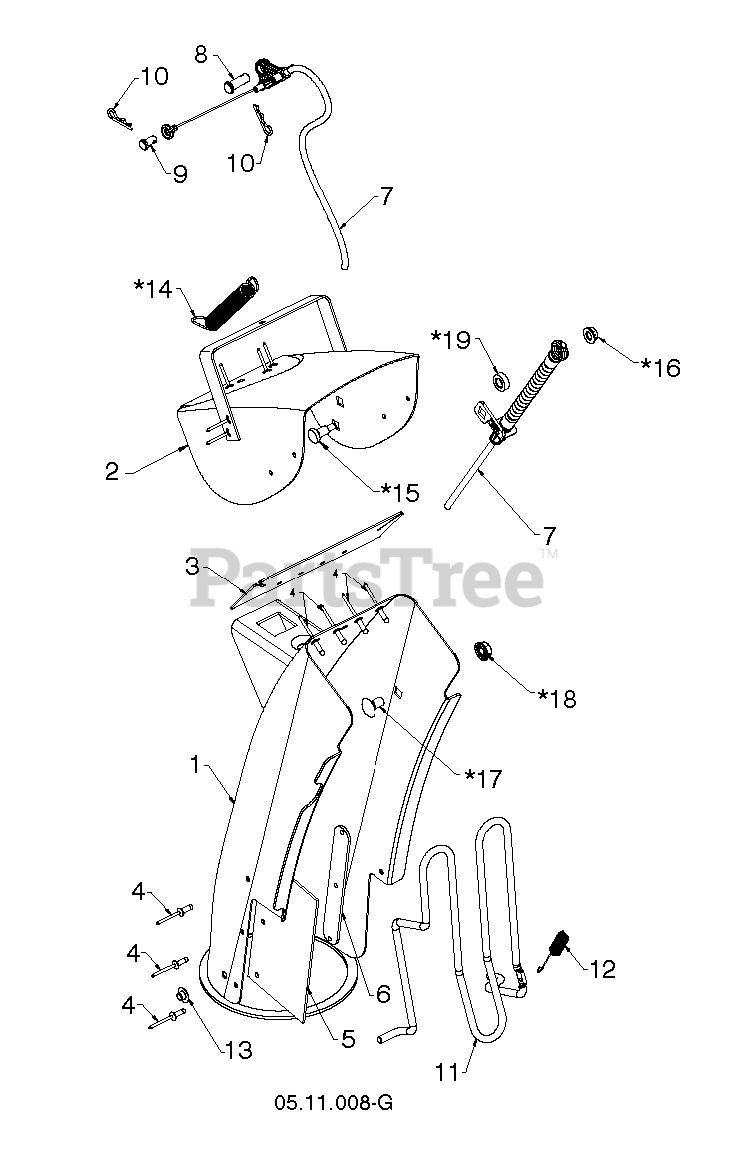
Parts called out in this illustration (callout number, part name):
1	ASM.CHUTE/DEFLECTOR.668
7	CABLE CONTROL.CHUTE.DEFLECTOR.
8	PIN CLEVIS 5/16X.875
9	PIN CLEVIS .25 X .31
10	HAIRPIN.SOFT.ZINC.059X1.125
11	ROD.GUARD.CHUTE (2 2)
12	SPRING.CHUTE.GUARD
13	NUT
